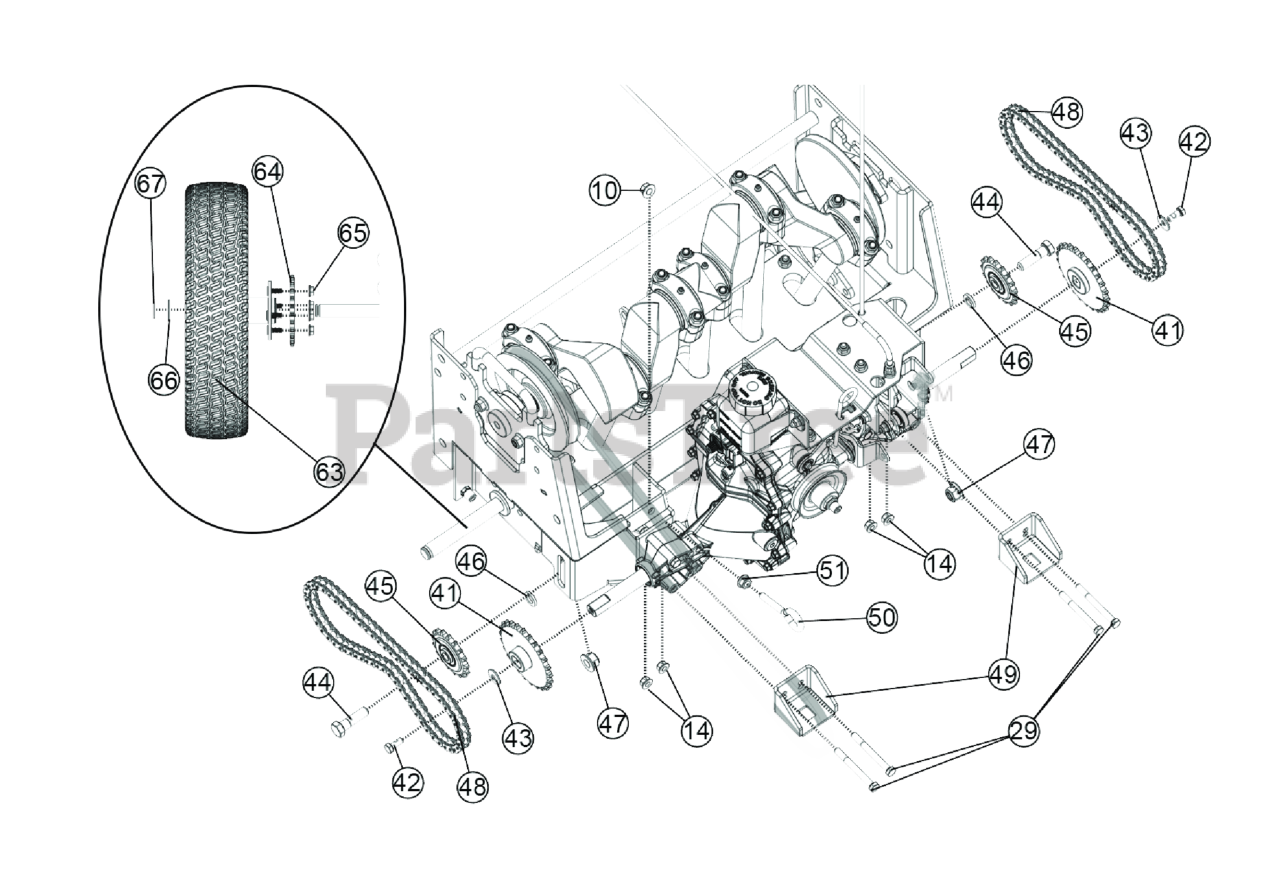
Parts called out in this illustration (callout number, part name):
10	NUT-HEX-NYLK, FLG .375"-16 ZP
14	NUT-HEX-NYLK, FLG .3125-18 ZP
29	SCREWCAP 5/16"-18 X 3" HCS ZP
41	WA, SPROCKET WHEEL DRIVE
42	SCREWCAP 5/16"-24X3/4" HCS G5 ZP
43	WSHR-STL, BLV .322" X .938" X .072" MZ
44	SCREWCAP 1/2"-13 X 1 3/4" HCS ZP GR. 5
45	SPROCKET, IDLER 17T X 1/2" BORE
46	WSHR-STL,FLT .500"X.875"X.134" MAB ZP
47	NUT-HEX-NYLK, FLG .500"-13 ZP
48	CHAIN, #40 X 61 PITCHES
49	WA, FRONT TRANS MNT
50	BLT-HOOK, .375"-16 X 3.75" OAL W/NUT
51	NUT WASHER FACE
63	ASM, WHEEL & TIRE PLUGR TURF
64	SPROCKET, RWD 25T 40
65	NUT FLANGE 5/16"-18 ZP
66	WASHER .765" ID X 1.25 OD X .06"
67	RING RETAINING "E" 3/4"
